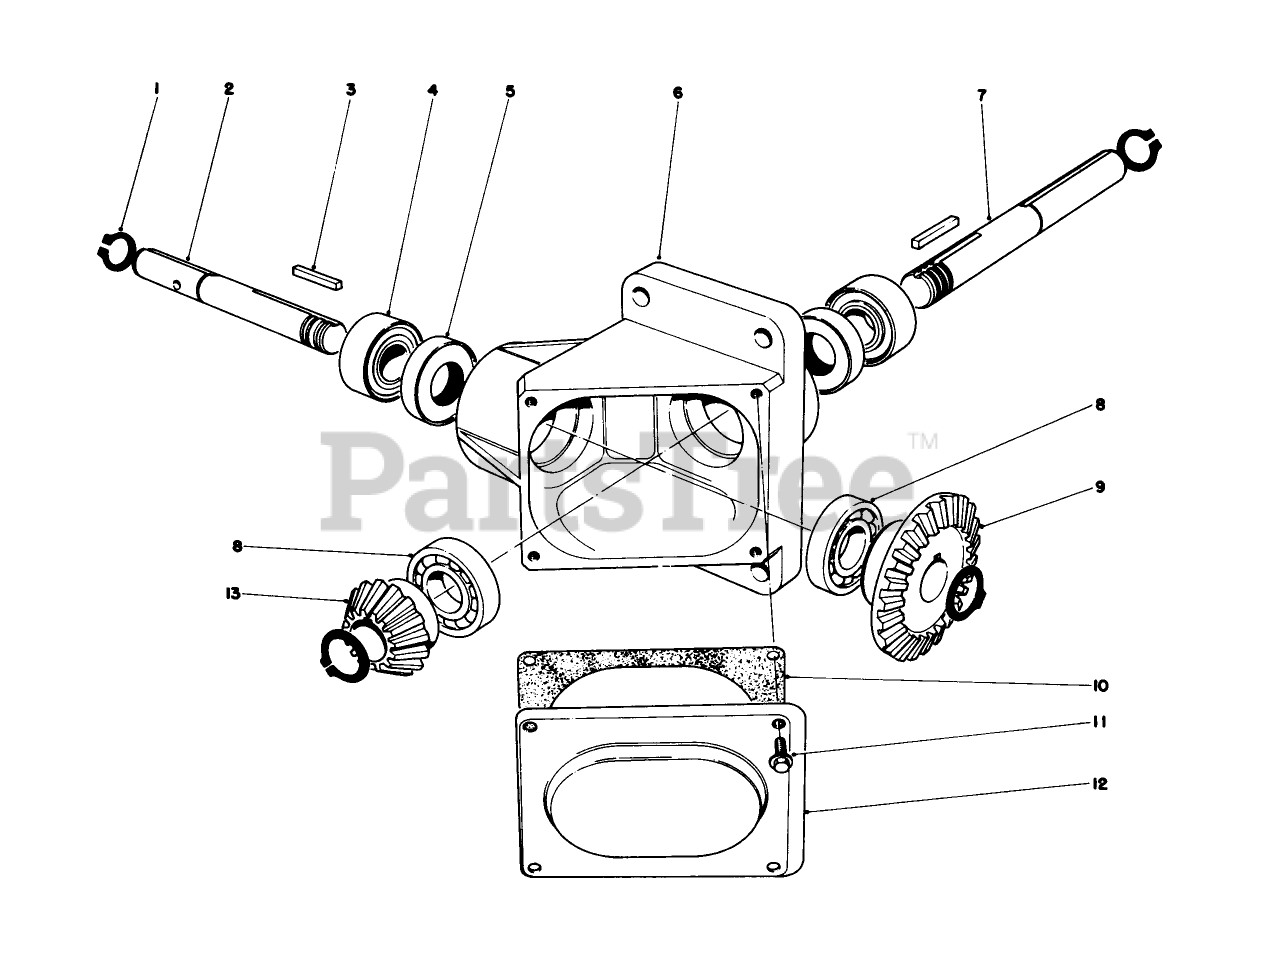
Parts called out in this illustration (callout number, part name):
1	Ring-Snap
2	GEAR BOX SHAFT (60120
3	Key
4	ROLLER BEAR (60124)
5	Oil Seal
6	GEAR BOX HSG
7	SHAFT-GEAR BOX
8	BEARING (R-12)
9	BEVEL GEAR (60128)
10	GASKET (60129)
11	SCREW
12	Cover Plate
13	BEVEL GEAR (60121)
